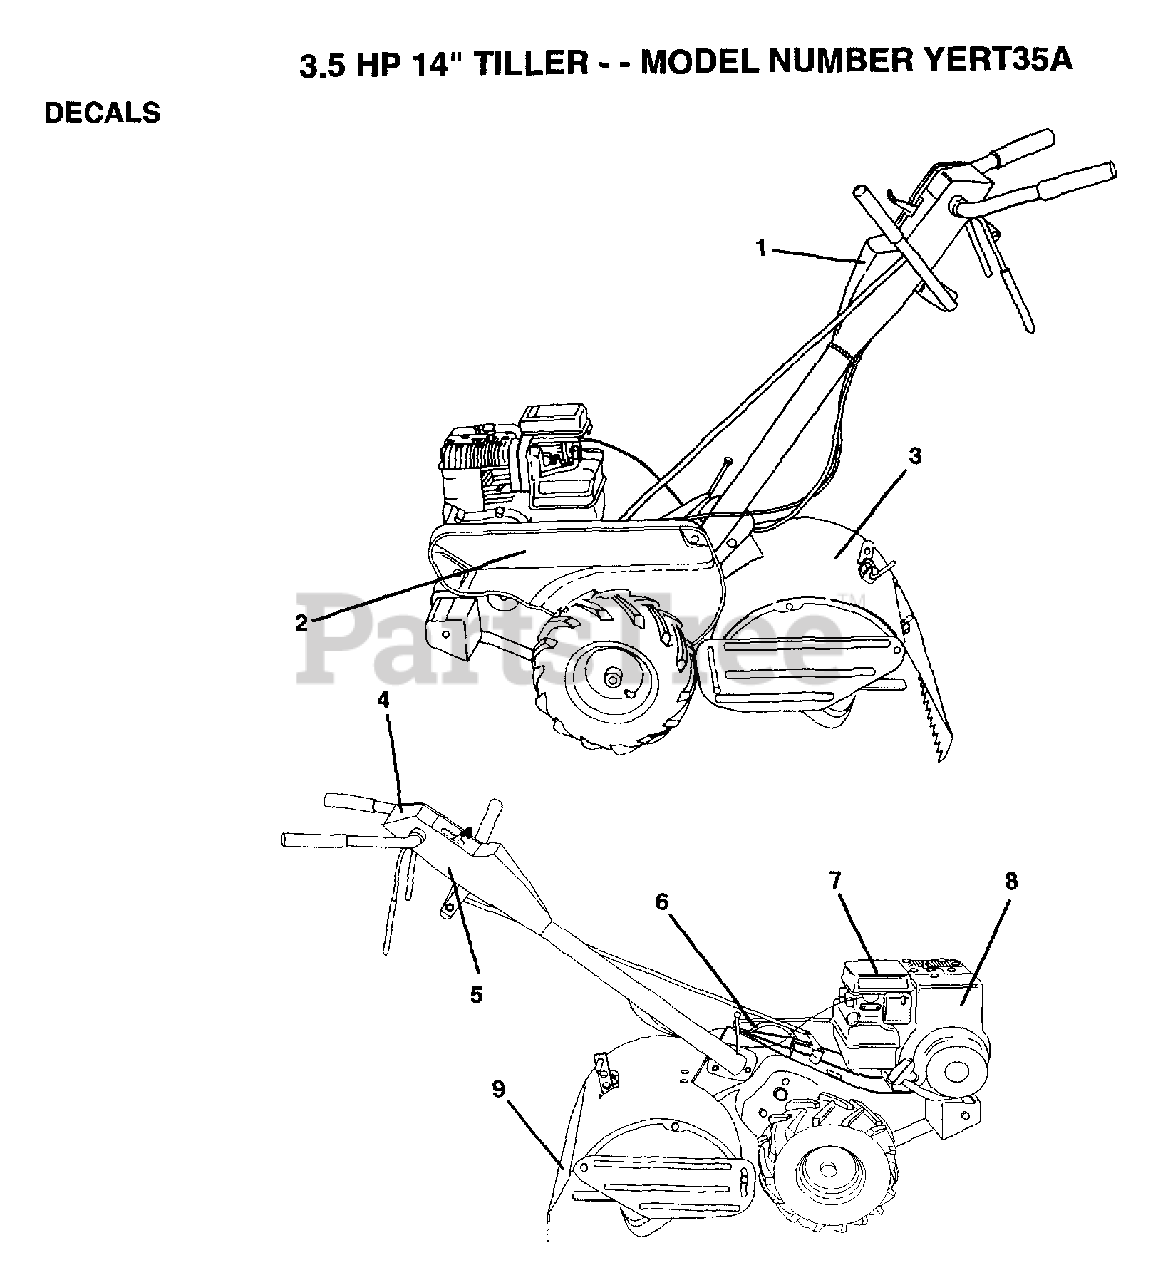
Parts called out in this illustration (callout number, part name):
1	DECAL.PNL.CONTROL
2	DECAL.SHLD.TINE.
3	DECAL.GUARD.BELT
4	DECAL.INSTRUCTION
5	DECAL TI
7	DECAL TI
8	"DECAL,ENG HP"
